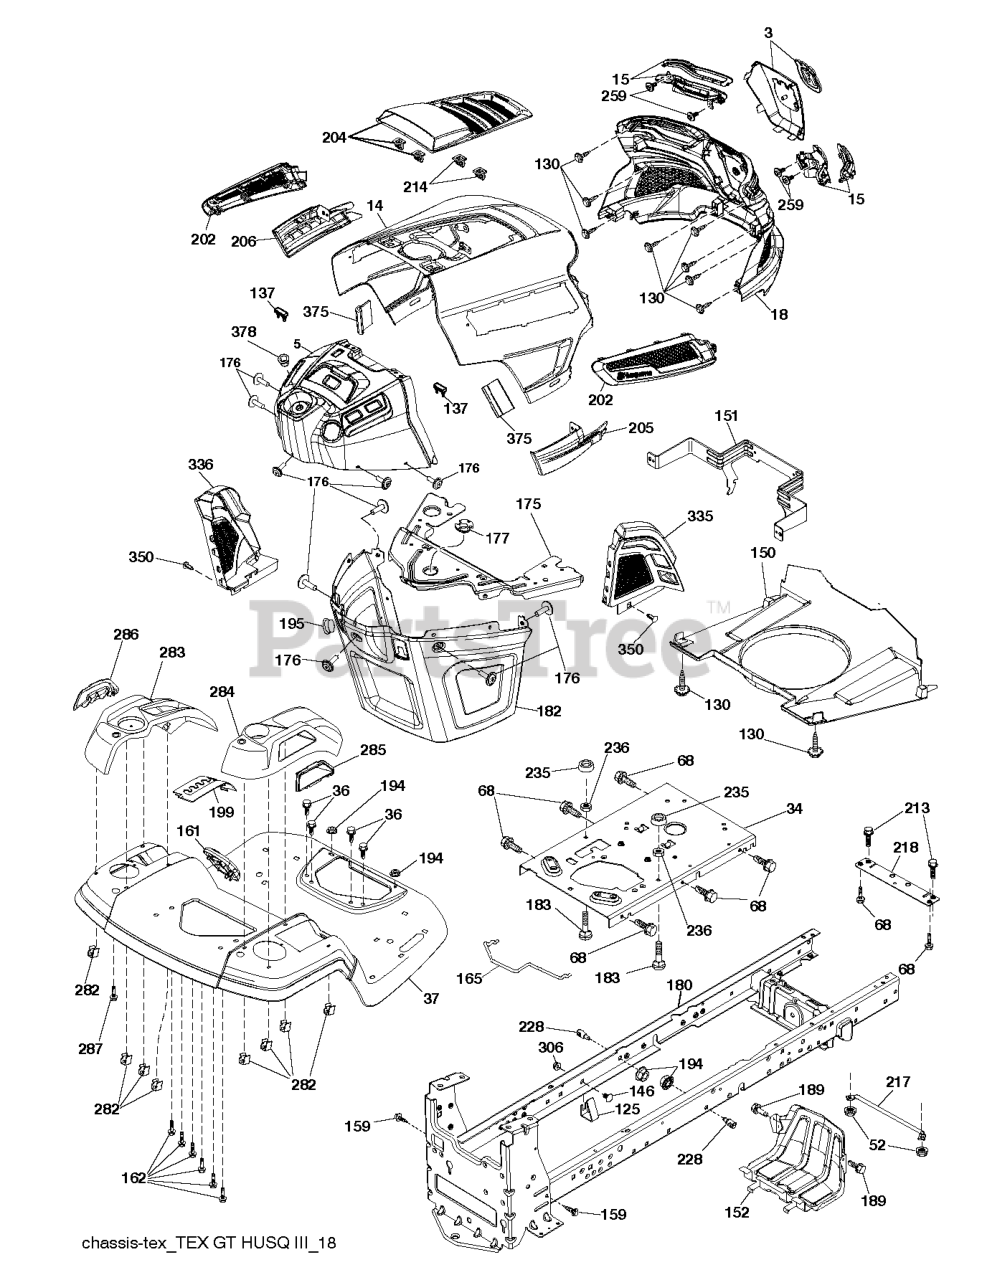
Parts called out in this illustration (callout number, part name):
5	DASH.UPR.GT2.SM.PTO.MC.HR.498
14	HOOD.ASM.HUSQVARNA.GT.TEX.ORAN
15	Service Kit
34	PLATE.ENGINE.WELDED.CHASSIS
36	SCREW 5/16"
37	FENDER.TLT.FS.W/CPH/FW/RSF.668
125	CLIP.FUEL.LINE
137	BUMPER DASH
146	BOLT.RDHD.SHT.SQNK.3/8-16X5/8
150	AIR.DUCT.GTV.BLACK
151	BRACKET.PIVOT.HOOD.GT.HUSQ.II
152	SHIELD.BROWNING.PNT.GT.V2
159	SCREW, 3/8-16X3/4
161	WINDOW.FUEL.LT.HUSQ.TEX.498
165	SUPPORT.TANK.REAR.W/TEX
175	PLATE.PNT.CROSSMEMBER.HUSQ/PRE
176	SCREW.#10-24X5/8.RN.QU
177	BUSHING STEERING
180	CHASSIS
182	DASH.LOWER.COMMON.12V.ADAPTOR
189	SCREW
195	PLUG.HOLE.DASH.LOWER.12V.BLK
199	PLATE.DECK.LIFT.HUSQ.LT
205	SIDE.TRIM.RH.GT.HUSQ.II
206	SIDE.TRIM.LH.GT.HUSQ.II.GRAY
213	SCREW HEXAGON HEAD SCREW 5/16-
214	CLIP.RETAINER.TINNER.
217	ROD.PIVOT.HOOD
218	X-PIECE.HOOD.STOP.NON/
228	STUD.W/"D"ANTI-ROTATION
236	NUT.CENTERLOCK.5/16-
282	CLIP.RETAINER.CONSOLE.LT.HUSQ
283	CONSOLE.ASM.LFT.RSF.HUSQ.LT
284	CONCOLE.CNTRL.PDL.HUSQ.LT.498
285	CONSOLE INSERT RH
286	CONSOLE.INSRT.LH.HUSQ.LT.BLACK
287	SCREW 1/4X20
306	NUT LOCK FLG 3/8-16 UNC
335	COVER.LOWER.DASH.RH.BLACK
336	COVER-LH.LOWER.DASH.GT2.BLACK
350	CLIP.X-MAS.TREE
375	BUMPER CLIP-ON. DASH 1"
378	BUSHING FLANGE; PLASTIC
